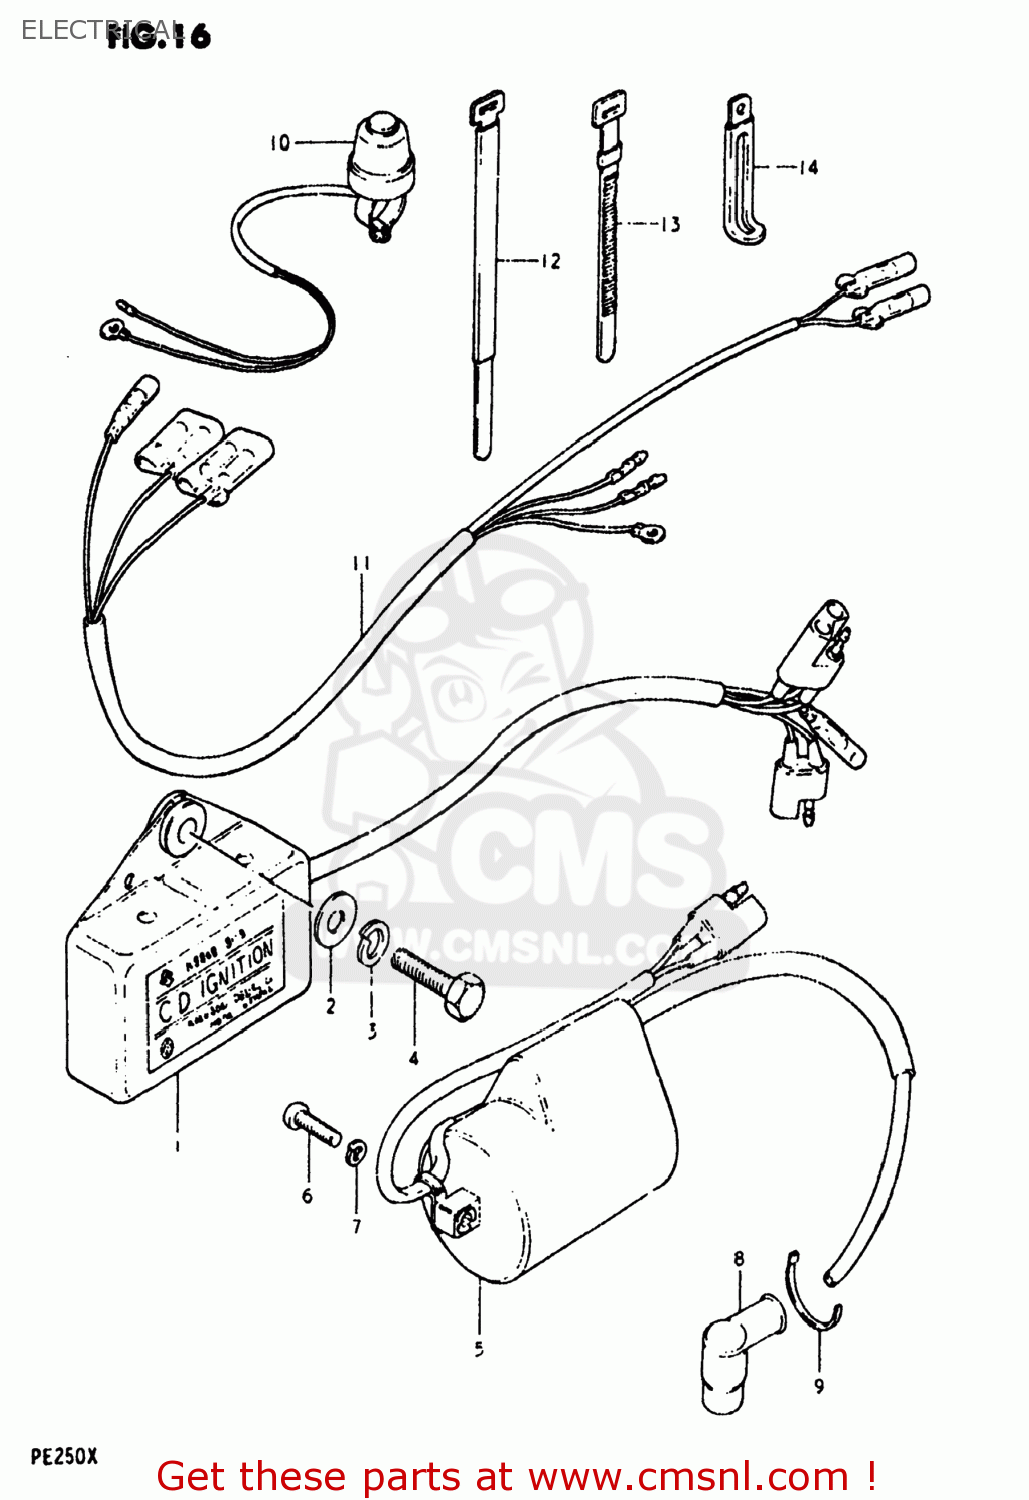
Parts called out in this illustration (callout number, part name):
1	CDI UNIT ASSEMBLY
2	WASHER(6.5X16X1.2)
3	LOCK WASHER
4	BOLT
5	COIL ASSEMBLY,IGNITION
6	SCREW 5X20
7	LOCK WASHER
8	CAP,SPARK PLUG
9	CLAMP
10	SWITCH ASSEMBLY
11	HARNESS,WIRING
12	CLAMP
13	CLAMP(L:120)
14	CLAMP
